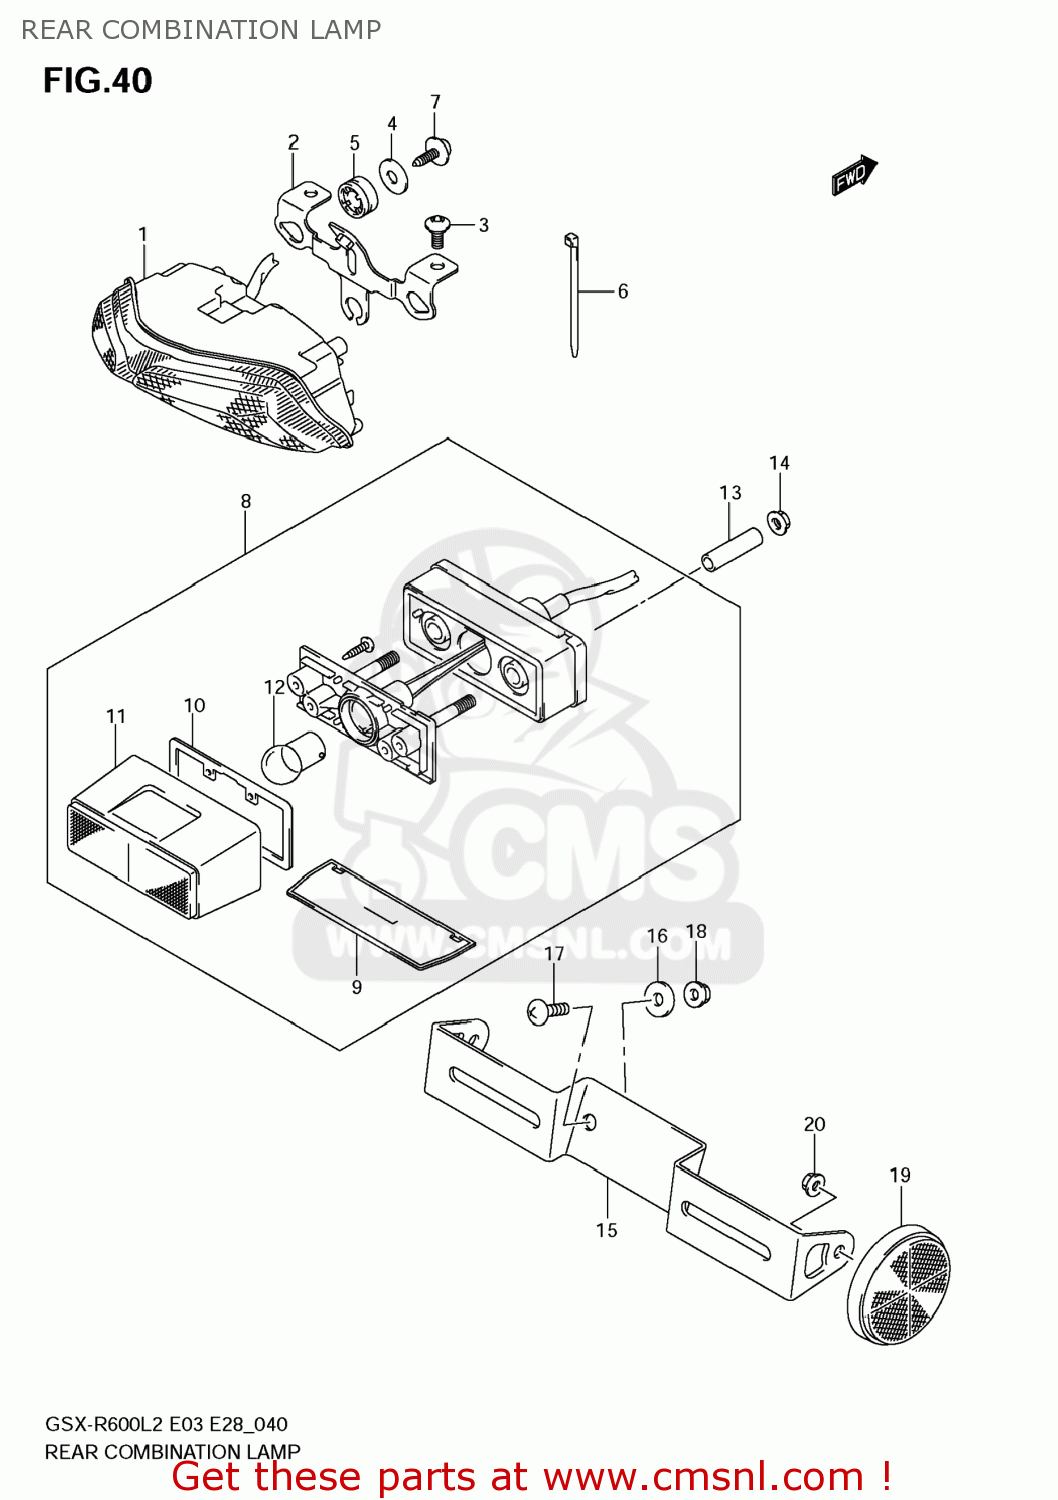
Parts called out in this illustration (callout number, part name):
1	LAMP ASSY,RR COMBINATION
2	BRACKET,RR COMBINATION LAMP
3	BOLT(5X13)
4	WASHER(5.5X20X1.2)
5	CUSHION
6	CLAMP(L:100)
7	SCREW
8	LAMP ASSY,LICENSE
9	LENS,LICENSE LAMP
10	GASKET (NAS)
11	COVER,LICENSE LAMP
12	BULB(12V5W,BF150-40160A)
13	SPACER(6.5X9X34)
14	NUT
15	BRACKET,LICENSE PLATE
16	WASHER(6.5X20X1.2)
17	SCREW
18	NUT
19	REFLECTOR ASSY,RR SIDE
20	NUT
